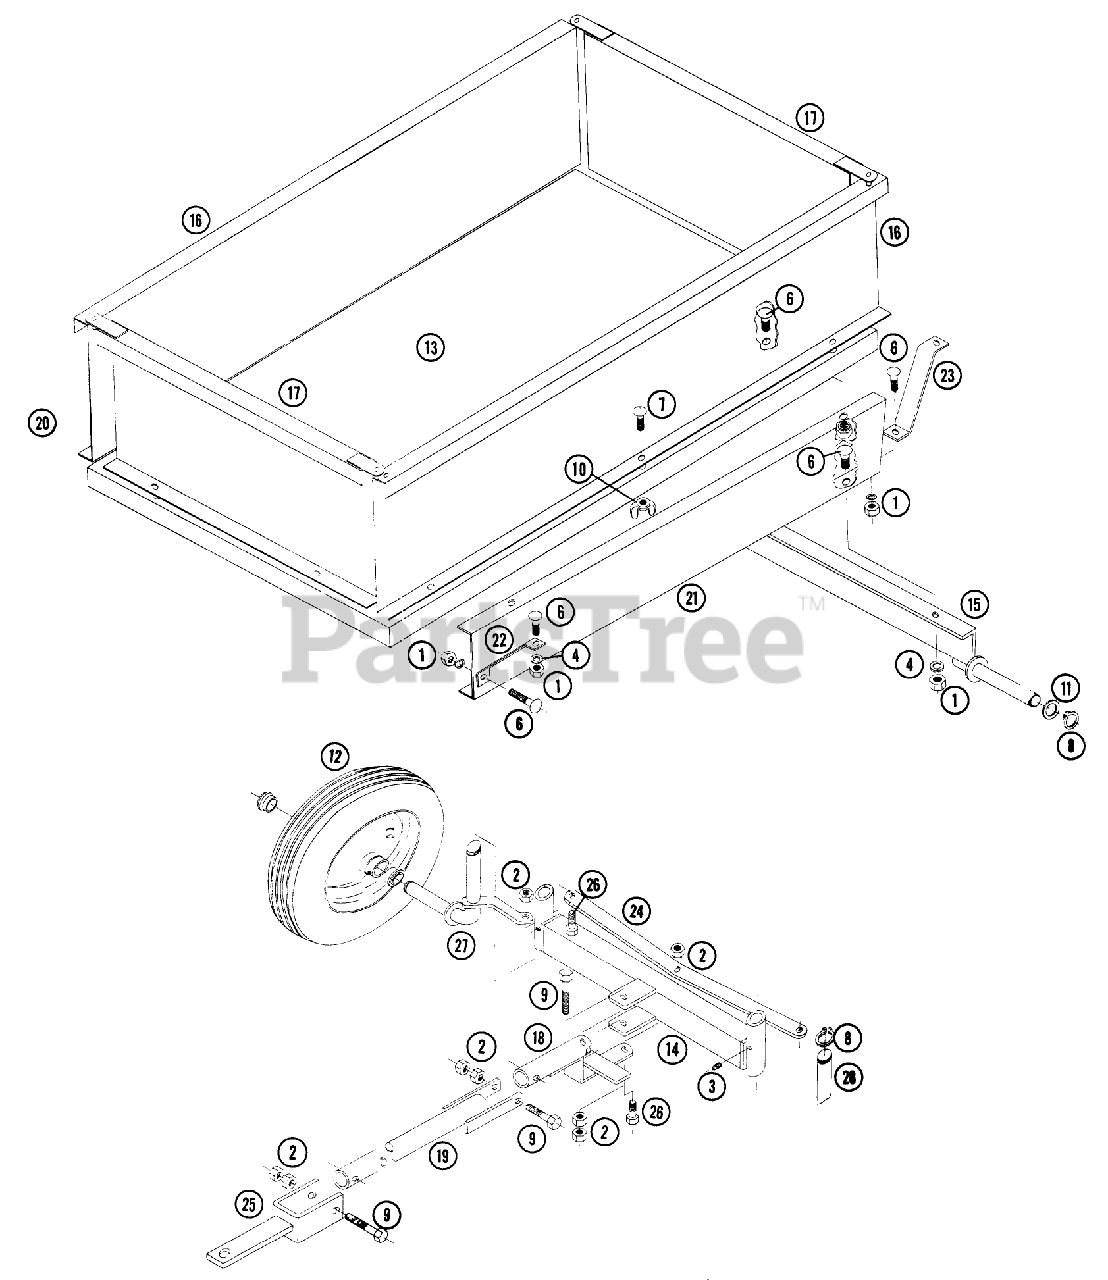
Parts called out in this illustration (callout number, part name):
1	Hex Nut
1	Bed, 32 x 64
2	End Gate
3	Side Board
4	Lockwasher
4	Eye Bolt w/Nut
7	Bearing Cone
7	Frame, Bed
8	Cap Screw, 3/8 x 2 1/2
9	Hex Hd. Cap Screw 1/2-13 x 2 1/2
9	Hex Nut
10	01163 1968 OPC
10	Lockwasher
11	WASHER
11	Washer
13	Bed
13	Spindle, right
14	Front Axle Assembly
14	Spindle, left
15	Tie Rod Assembly
16	Shaft
16	Clevis Pin, 3/8 x 1
17	End Panel
17	Clevis
18	Swivel Hitch Assembly
18	Washer, 3/8
19	Draw Bar Assembly
19	Clevis Pin, 3/8 x 2
20	Clip
20	Cotter Pin, 3/32 x 1
21	Bed Support L.H.
22	Front Brace
22	Steering Tongue
23	Rear Brace
23	Draw Bar
24	Tie Rod
24	Eye Pin
25	Tractor Swivel Hitch Ass-y.
26	Clevis Pin
27	Front Spindle R.H.
